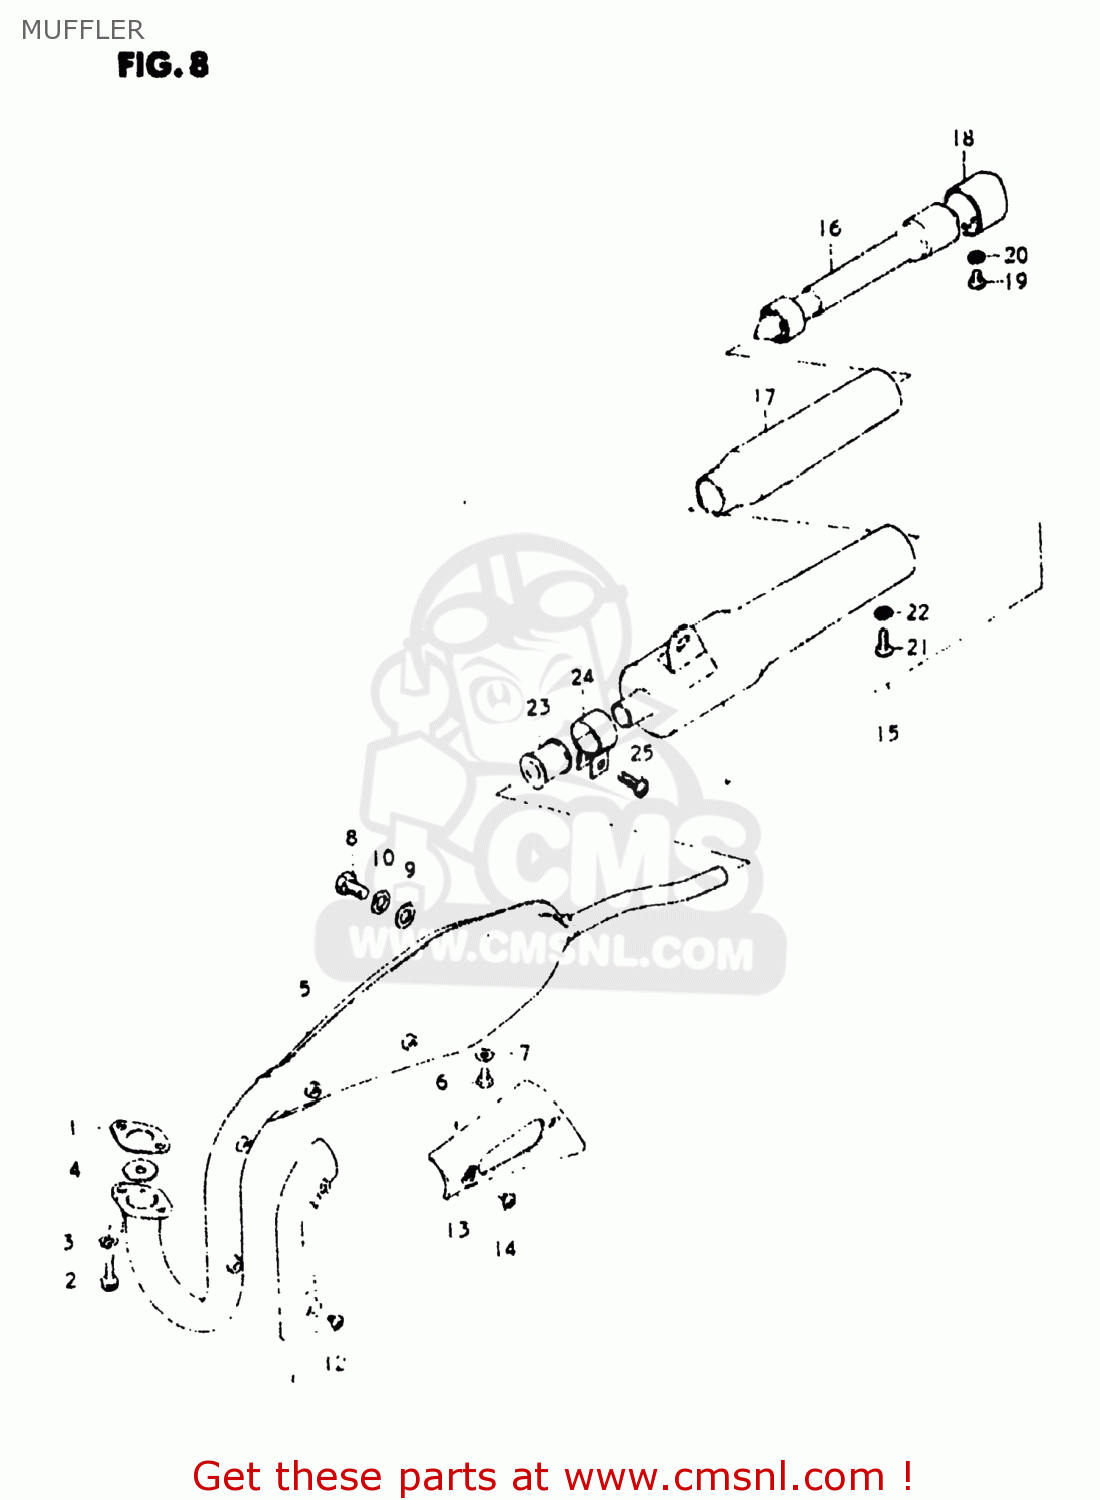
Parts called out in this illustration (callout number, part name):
1	GASKET,EXHAUST PIPE
2	BOLT
3	LOCK WASHER
4	PLATE,EXHAUST PIPE
5	MUFFLER ASSEMBLY
6	BOLT
7	WASHER
8	BOLT
9	WASHER (8.2X20X1.6)
10	LOCK WASHER
11	COVER,EXHAUST PIPE
12	SCREW
13	COVER,MUFFLER
14	SCREW
15	MUFFLER ASSEMBLY
16	TUBE,CLEAN OUT
17	SHELL,ARRESTER
18	CUTTER,MUFFLER TAIL
19	SCREW
20	LOCK WASHER
21	SCREW
22	LOCK WASHER
23	CONNECTOR,MUFFLER
24	CLAMP
25	SCREW
